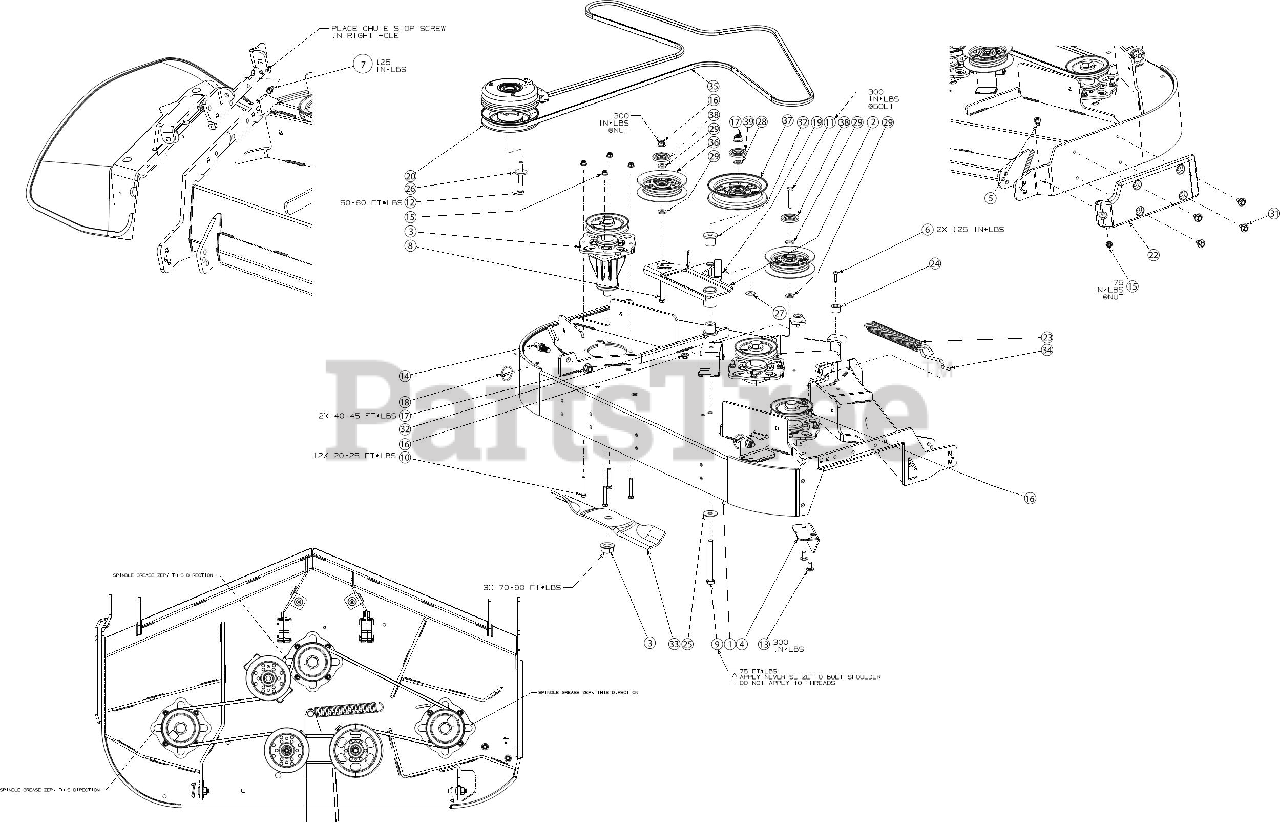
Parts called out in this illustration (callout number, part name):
1	48" FAB DECK ASSEMBLY
2	IDLER ARM ASSEMBLY
3	SPINDLE ASSEMBLY
4	DECK CHUTE BAFFLE
5	CARRIAGE BOLT 5/16-18 x 1.00
6	SCREW 1/4-20 x 1.0
7	SCREW 1/4-20 X.500
8	HEX SCREW-3/8-16X2.5 GR5
9	SCREW 1/2-13 x 4.5 GR 5
10	SCREW 5/16-18 x 2.0 GR5
11	SCREW 3/8-16 x 2.0 GR5
12	SCREW 7/16-20 x 3.25 GR5
13	CARRIAGE BOLT 3/8-16 x .75
15	FLANGE LOCK NUT 5/16-18
19	COTTER PIN 3/32
20	ELECTRIC PTO CLUTCH
22	DECK SKID PLATE (LH)
23	EXTENSION SPRING
25	WASHER .51 x 1.5 x .07
26	FLAT WASHER .445 x 1.248 x .170
27	FLAT WASHER
28	FLAT WASHER
29	FLAT WASHER
31	SHOULDER SCREW .43X.29X5/16-18 TT
32	SHOULDER SPACER
33	17" BLADE (HI LIFT)
34	DECK SPRING HOOK
35	DECK BELT A SEC x 137"
36	IDLER PULLEY 4.0
37	IDLER PULLEY 5.0"
38	IDLER PULLEY CAP
39	PULLY CAP 1/2"
